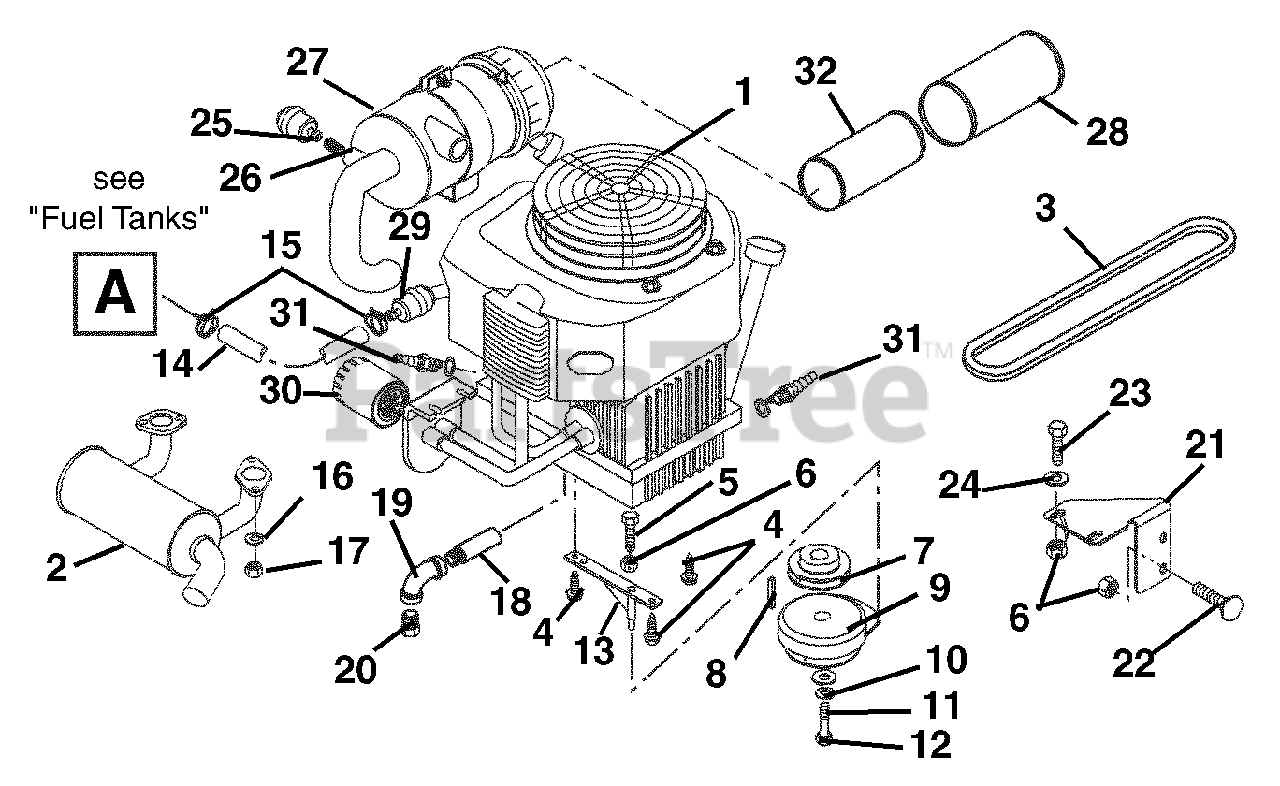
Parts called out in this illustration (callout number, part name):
1	ENG,25HP KOHLER W/RMT OILFILTR
2	MUFFLER, KOHLER
3	V-BELT, HA-RAW EDGE
4	@SCR-TAP .38-16X1.00 HWH TR YZ
5	@BLT-HEX .31-18X1.50 GR5 YWZC
6	@NUT-LK-TOP-FLG .31-18 YWZC
7	PLY-V 4.00 X 1.12 KEYWAY 1.54
8	KEY-SQ .25X.625X.25 SAE 8630
9	ELECTRIC CLUTCH
10	WSHR-FL-STL .515X1.625X.250 YZ
11	@WSHR-LK .44X.109 REG YWZC
12	BLT-HEX .44-20X2.50 GR5 YWZC
13	WMT, CLUTCH ANCHOR
14	GAS LINE-BULK 1/4" I.D.
15	CLAMP-HOSE WIRE .490/.510X.116
16	@WSHR-LK .31X.078 REG YWZC
17	NUT-HEX M8-1.25 YWZC
19	ELBOW .375-18 NPTF
20	PIPE PLUG
21	BRKT, OIL FILTER MTG - BLACK
22	@BLT-RHDSSQNK .31-18X.62 G5YZ
23	@BLT-HEX .31-18X1.00 GR5 YWZC
24	@WSHR-FL-STL.38X.875X.083 YWZC
25	FILTER MINDER
26	NIPPLE, 1/8"NPT
27	AIR CLEANER ASSEMBLY
28	ELEMENT, OUTER PRIMARY
29	FILTER, FUEL
30	FILTER, OIL - KOH CV20
31	SPARK PLUG
32	ELEMENT, INNER SAFETY
